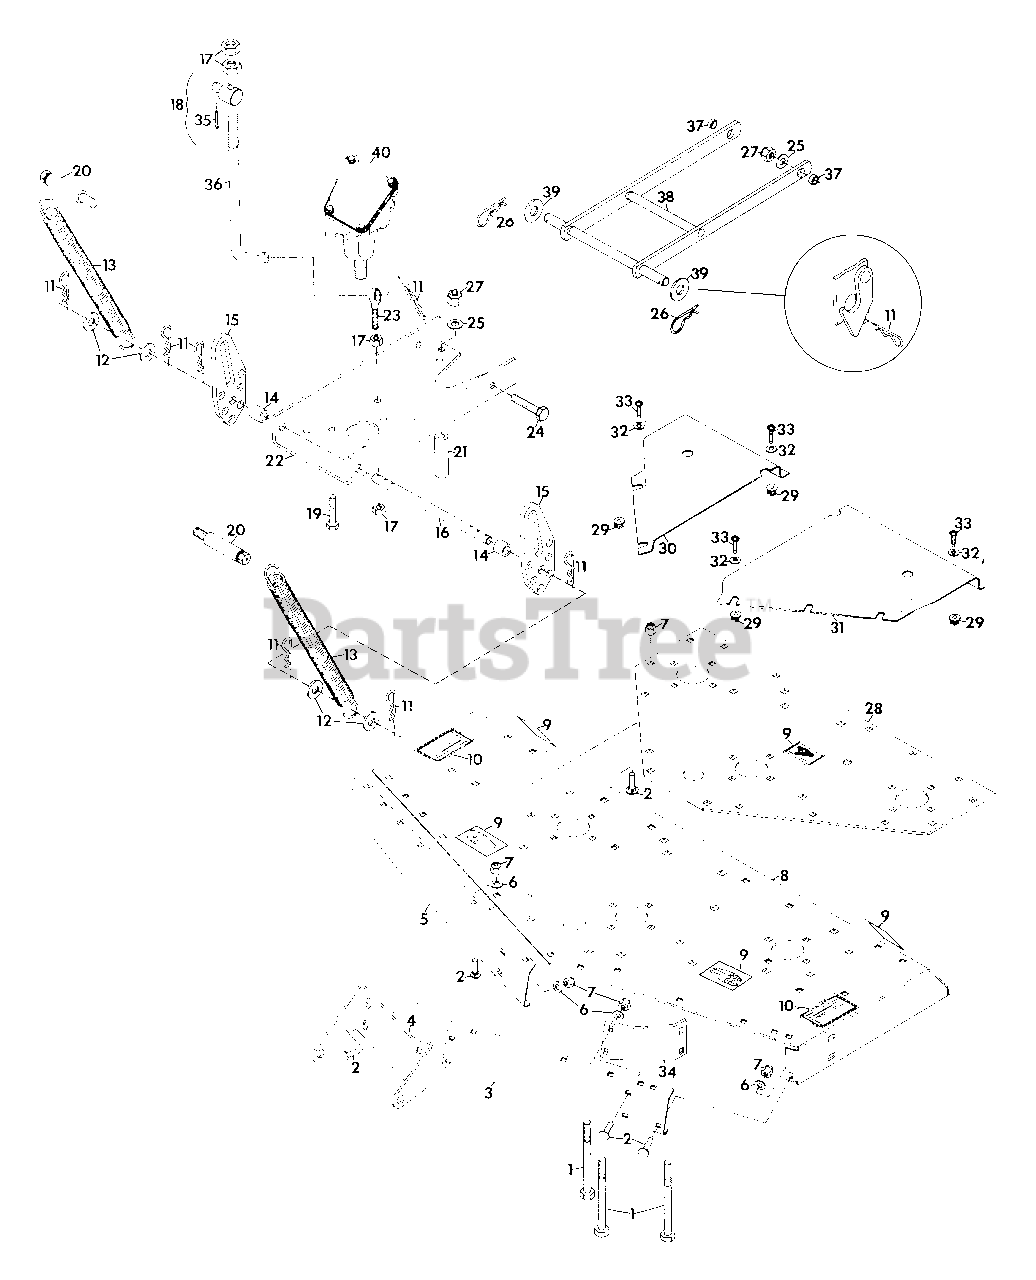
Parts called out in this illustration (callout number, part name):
1	Bolt Hex 1/2-13 x 3.500
2	Bolt 3/8-16 x .875 RD HD SQ NK
3	Plate, Front Cover L.H.
4	Bracket, Roller Front
5	Plate, Front Cover R.H.
6	Washer, Flat .406 x .812 x .065
7	Nut, Lock; 3/8-16
8	Weldment, 60 Inch Deck
9	Decals, Height Adj. & Belt Layout
10	Decal, Danger
11	Cotter, Hair Pin
12	Washer, Flat .656 x 1.312 x .095
13	Spring
14	Spacer, Rod
15	Plate, Leveling
16	Rod, Support Plate
17	Nut, Jam 1/2-13 Hex
18	Assembly, Mower Lift Pivot
19	Bolt, Hex; 1/2-13 x 1.000
20	Pin Latch
21	Spacer
22	Plate; Support
23	Bolt, Eye
24	Bolt Hex 1/2-13 x 1.750
25	Washer, Flat .531 x 1.062 x .095
26	Pin, Hair
27	Nut, Lock; 1/2-13
28	Plate, Deck Support
29	Grommet, Plastic
30	Cover, Belt R.H.
31	Cover, Belt L.H.
32	Washer, Flat .281 x .625 x .065
33	Screw, Mach 1/4-20 x .625 RD HD
34	Baffle, Front
35	Pin, Groove; .125 x .625
36	Rod, Lift
37	Bushing
38	Weldment, Pivot Arm
39	Washer, Flat .813 x 1.375 x .100
